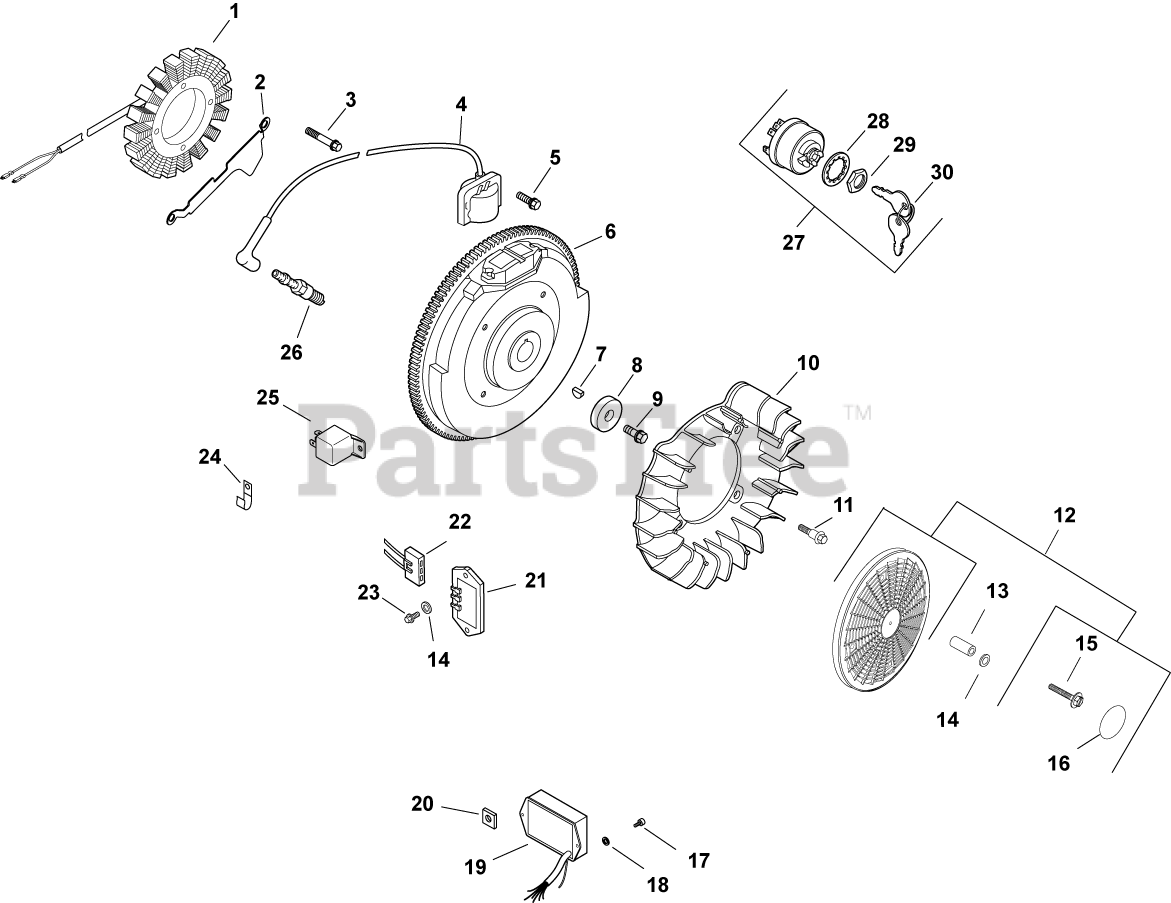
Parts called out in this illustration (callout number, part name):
1	KIT, 15 / 20 AMP STATOR
2	BRACKET, STATOR WIRE
3	SCREW, M5X0.8X25 - (#25086402S)
4	MODULE, IGNITION
5	SCREW, SKT THD FRM M5X0.8X25
6	FLYWHEEL ASSEMBLY - USE 24 025 14-S
7	KEY, 3/16" X 5/8"
8	WASHER, FLAT 13/32"
9	SCREW, FLG M10X1.5X45 - (#25086361S)
10	FAN (WITH HOLE)-USE 24 157 16-S
11	BOLT, SHOULDER
12	KIT, GRASS SCREEN
13	SPACER - DISCONTINUED
14	WASHER, FLAT 3/16"
15	SCREW, SLT HD CAP M4X0.7X25
16	DECAL, GRASS SCREEN USE 24 113 499-S
17	SCREW, PHL HD #11-16X1/2"
18	WASHER, FLAT 1/4" (O.D. 1/2")
19	MODULE, SPEED ADVANCE-DISCONTINUED SEE PB265
20	NUT, PLASTIC
22	CONNECTOR, BODY (KM)-USE 25 155 41-S
23	SCREW, PHL HD #11-16X7/8"
24	CLIP, CABLE
26	PLUG, SPARK (STD)
27	SWITCH ASSY, KEY (KM)-USE 25 099 32-S
28	WASHER, INTERNAL TOOTH
29	NUT, KEY SWITCH
30	KEY, SET -USE 48 340 01-S
2545403-S	TIE, WIRE
X-22-11-S	WASHER, INT TOOTH LOCK 1/4"
